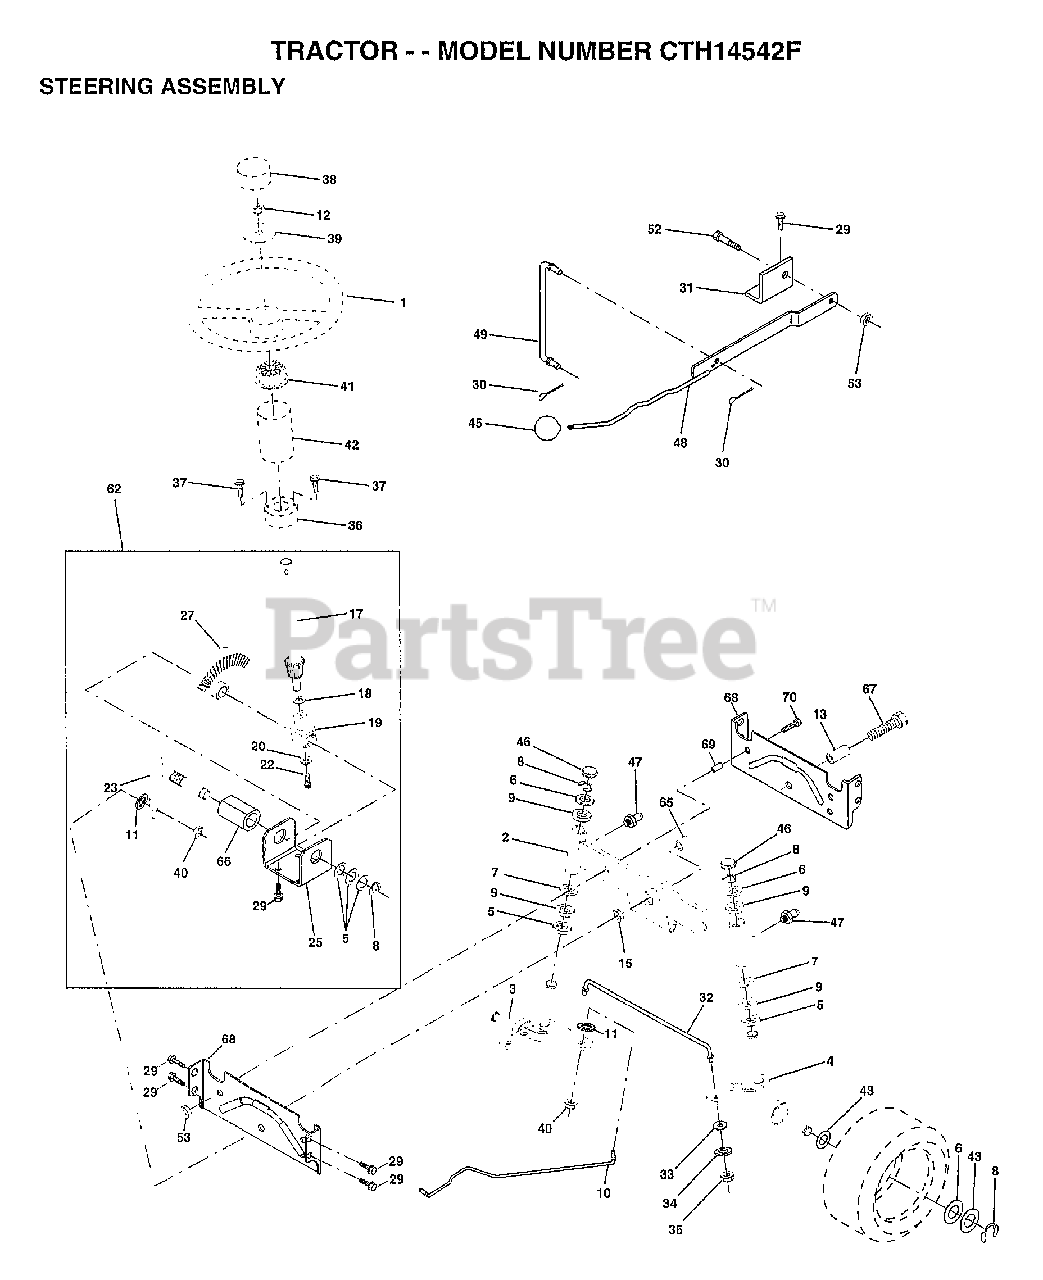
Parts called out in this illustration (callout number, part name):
1	WHEEL STR AYP BLK
2	AXLE ASM
3	SPINDLE.ASM.LH
4	"SPINDLE ASM,RH"
5	WASHER .T
6	WASHER
7	WASHER
8	RING
9	COL. SRTG. BEAR.
10	DRAGLINK-STAMPED
11	LOCKWASHER
13	BEARING
15	"NUT-LOC,FLANGE LT"
17	STEERING SHAFT
18	THRUST WASHER
19	SUPPORT.SHAFT
22	SCREW HEX SOC1/4-
25	BRKT-STEERING
27	GEAR SECTOR
29	SCREW
30	COTTER PIN
31	BRKT.PVT.MAN.LVR.
32	ROD.TIE.19.75
33	WASHER M
34	LOCKWASHER
35	NUT.LOCK.5/16-24
36	BUSHING.STRG.3/4
37	"SCREW-TT,10-32 FL"
38	CAP STEER AYP
39	WASHER
41	ADAPTER LT
42	BOOT SHAFT STEER
43	WASHER
45	KNOB T (1/2-HOLE)
46	CAP
47	ZERK M
48	LEVER.ASM.CLUTCH
49	LINK CLTCH W/NUTS
52	"BOLT, SHOULDER LT"
62	KIT STEERING ASM
65	SPACER AXLE
66	"BEARING-ARM,PITMA"
67	BOLT
68	BRACE AXLE
69	"SPACER BRCAE,AXLE"
70	BOLT, FIN HEX 3/8-16 UNC X 2-1/4
